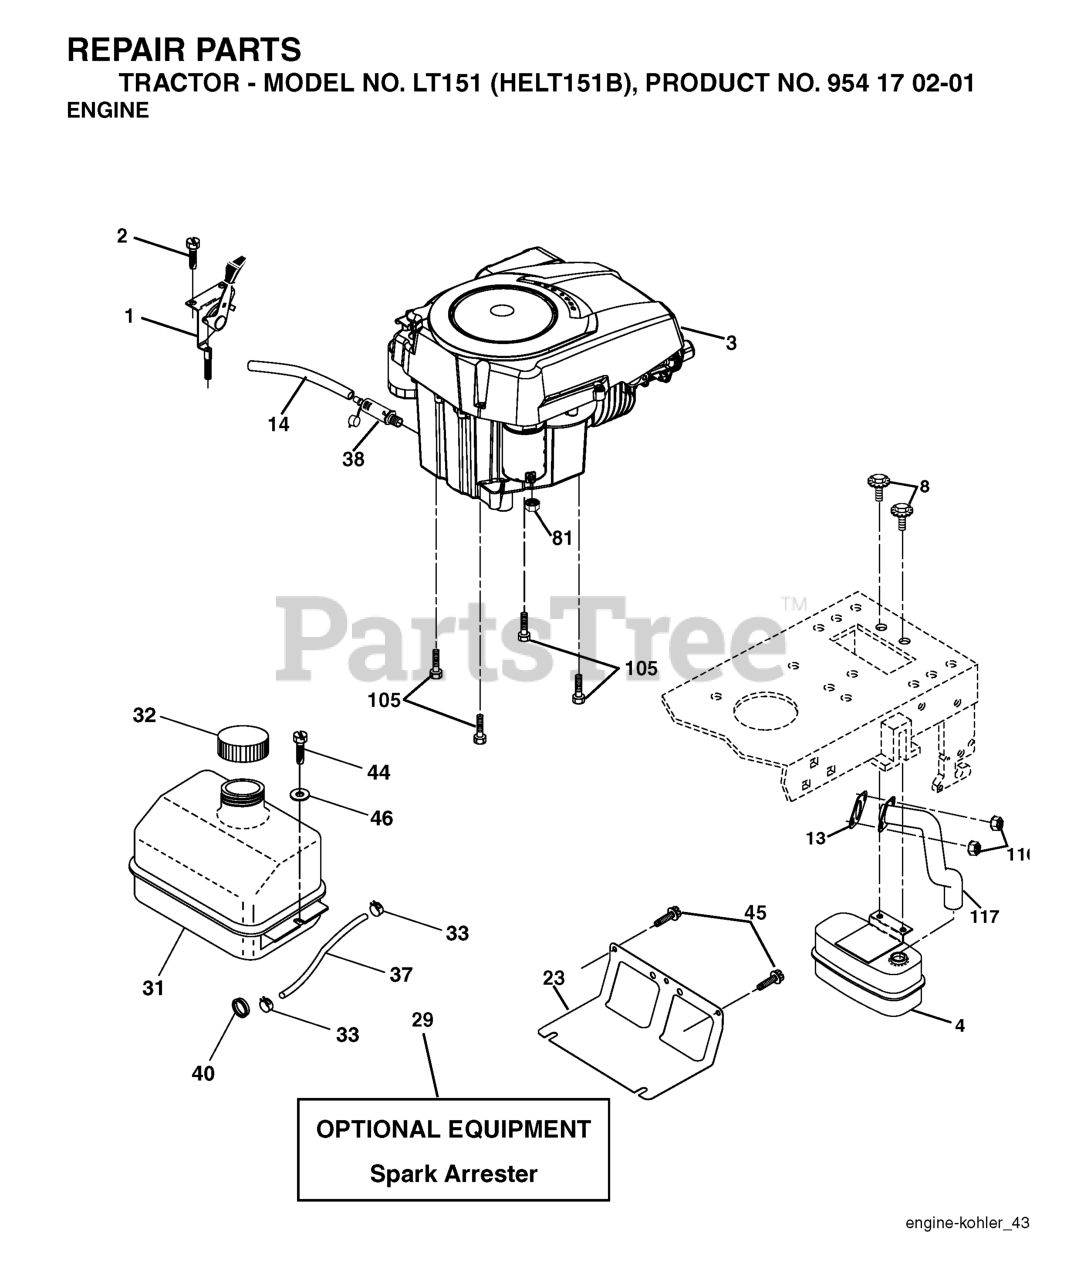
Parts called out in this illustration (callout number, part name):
1	CONTROL.THROTTLE.LT/YT
2	SCREW
4	MUFFLER.SINGLE.CYL.KOHL/B&S
8	BOLT.5/16-18UNCX3/4 W/SEMS.BLK
13	GASKET.EXHAUST.KOHLER
14	TUBE, DRAIN OIL ASM.
23	SHIELD.BROWNING.DBR.GUARD
29	KIT.SPARK ARRESTOR 794945 B&S
31	TANK.ASM.FUEL.FRONT.W/CAP
32	FUEL CAP
33	HOSE CLAMP
37	LINE.FUEL.20
38	PLUG DRAIN OIL EASY
40	BUSHING.SNAP.NYL.BLK.
44	SCREW HEXWSHR 1/4-20X3/4
45	SCREW, 3/8-16X3/4
81	NUT
105	SCREW 3/8-16X1
116	NUT.HEX.FLANGE.TOPLOCK
117	RP.TUBE.EXHAUST.KOHL.COURAGE
